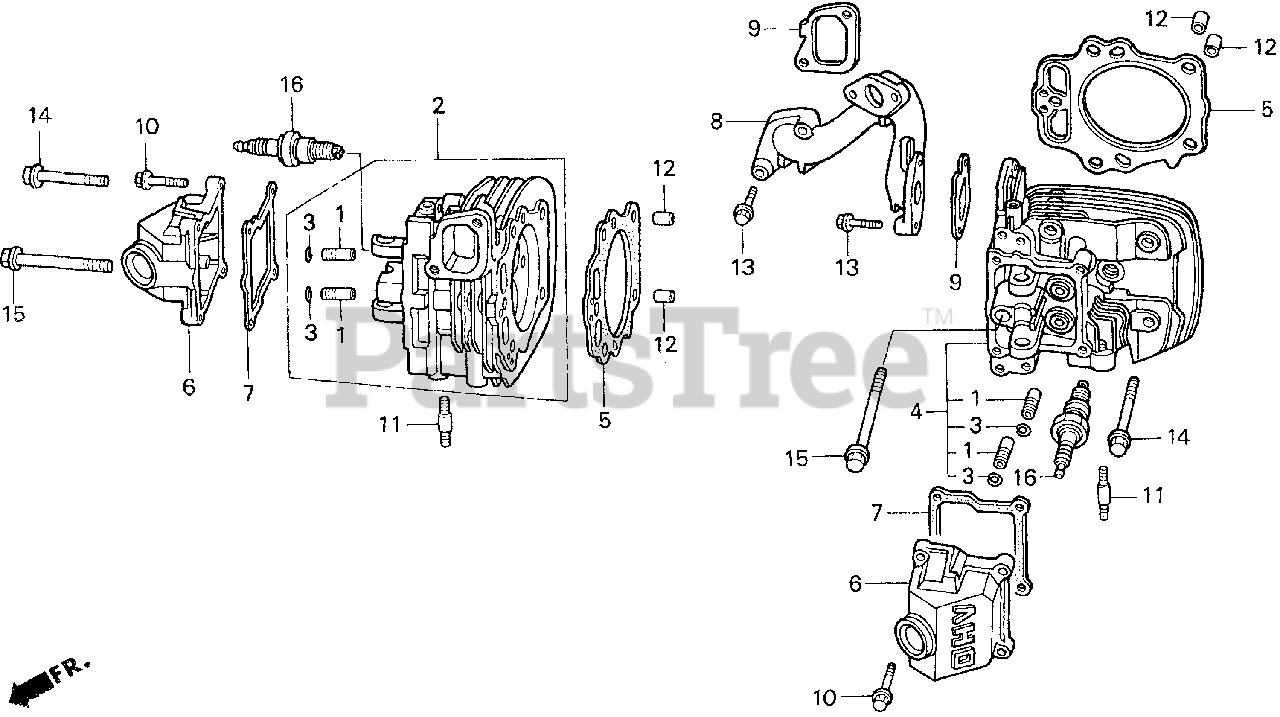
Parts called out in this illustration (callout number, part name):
1	GUIDE, EX. VALVE (OS)
2	CYLINDER HEAD
3	CLIP, VALVE GUIDE
4	CYLINDER HEAD
5	GASKET, CYLINDER HEAD
6	COVER, HEAD
7	GASKET, HEAD COVER
8	MANIFOLD, IN.
9	GASKET, IN. MANIFOLD
10	BOLT, FLANGE (6X25) (CT200)
11	BOLT, STUD (8X25)
12	PIN A, DOWEL (12X20)
13	BOLT, FLANGE (6X32)
14	BOLT, FLANGE (10X75)
15	BOLT, FLANGE (10X130)
16	SPARK PLUG (BPR5ES) (NGK)
